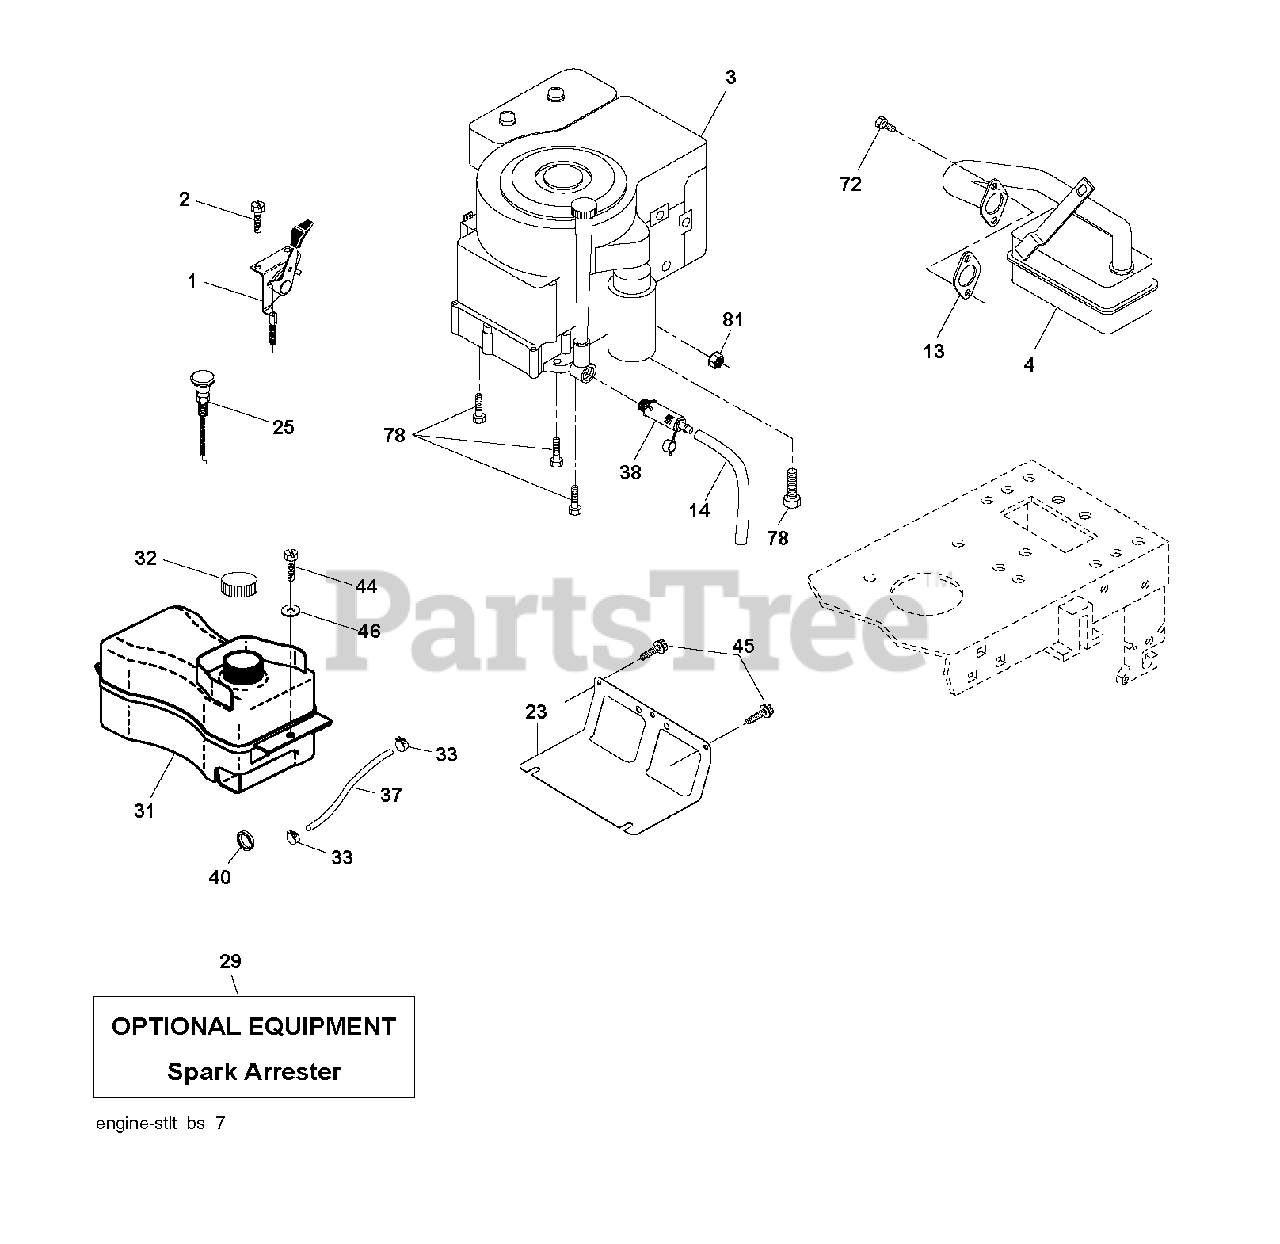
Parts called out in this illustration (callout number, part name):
1	CONTROL TH/CH FLAG
2	SCREW
13	REPL BY 532 27 22-93
14	TUBE, DRAIN OIL ASM.
23	SHEILD.BROWNING.DBR.GUARD
29	ARRESTER SPARK (OPTIONAL)
32	FUEL CAP
33	HOSE CLAMP
37	LINE.FUEL.20
38	PLUG DRAIN OIL EASY
40	GROMMET T
44	SCREW HEXWSHR 1/4-20X3/4
45	SCREW, 3/8-16X3/4
72	SCREW.SOCKET HD.5/16-1
78	SCREW.3/8-16
81	NUT
